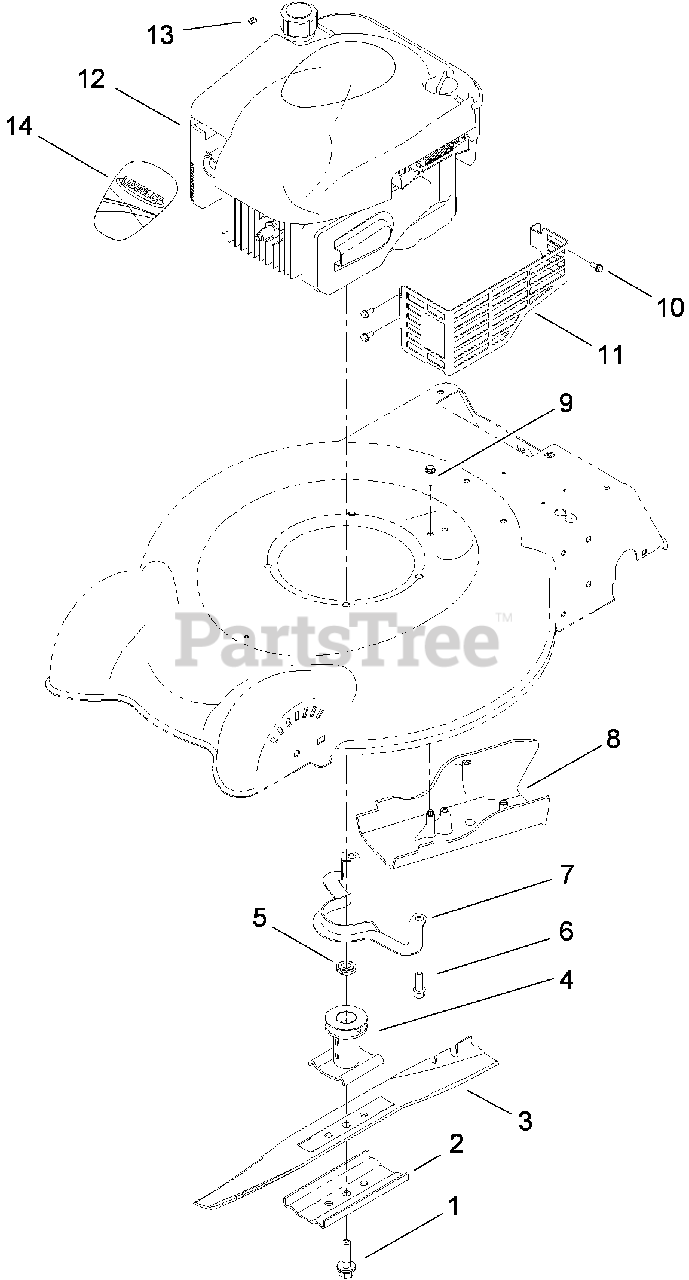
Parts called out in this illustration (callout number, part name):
1	BOLT-BLADE
2	SUPPORT-BLADE
3	BLADE-20 INCH
4	BLADE DRIVER ASM
5	Spacer-Driver
6	SCREW-TAPTITE
8	COVER-BELT
9	SCREW-HWH
10	SCREW-TAPTITE
11	SHIELD-MUFFLER
13	STOP-ROPE
14	DECAL-SHROUD
